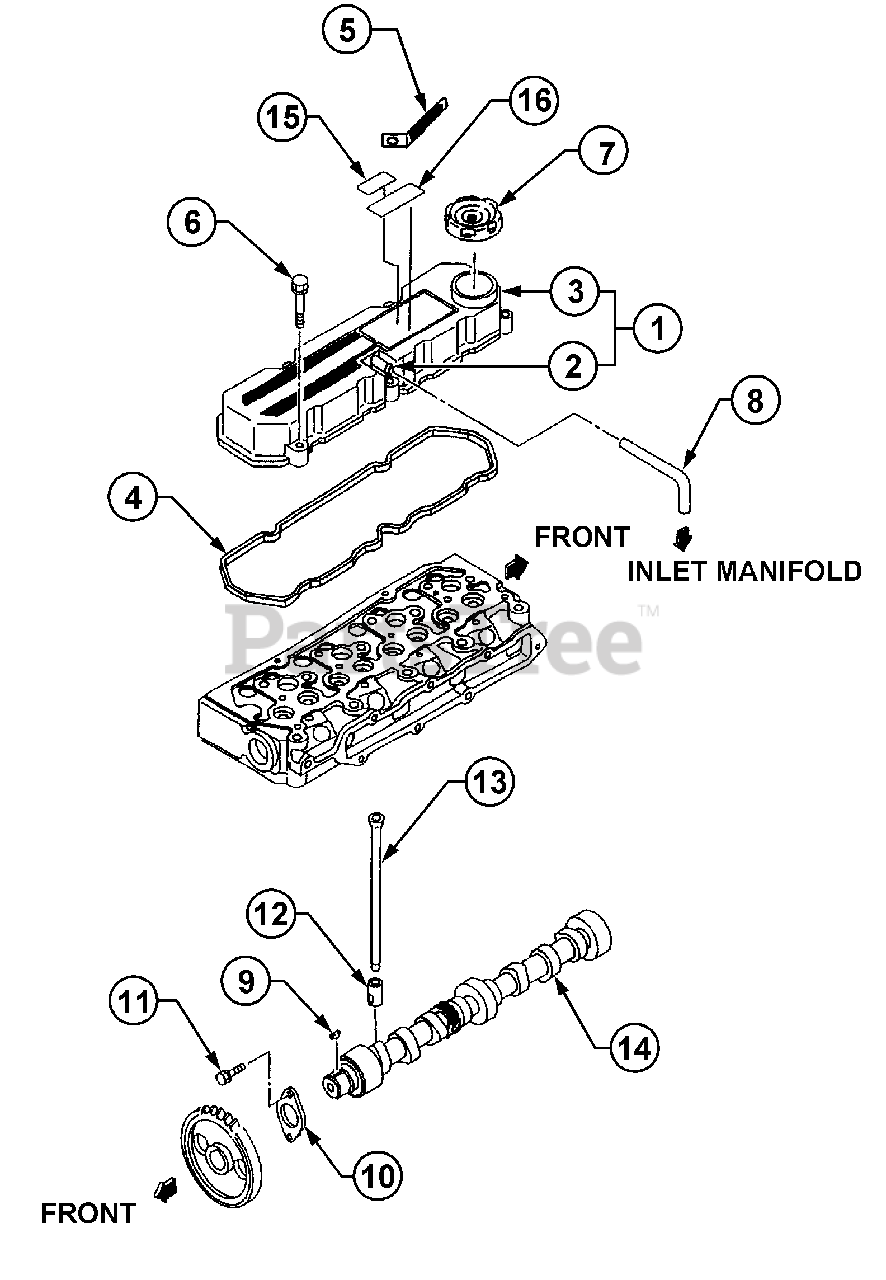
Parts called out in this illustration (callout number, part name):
1	Cover Assy, Rock
2	Pipe
3	Cover, Rocker
4	Gasket, Cover
6	Bolt, w/Washer
7	Cap, Oil Filler
8	Breather, Pipe
9	Key, Woodruff
10	Plate, Thrust
11	Bolt, w/Washer
12	Tappet
14	Camshaft
16	Label, Engine No.
